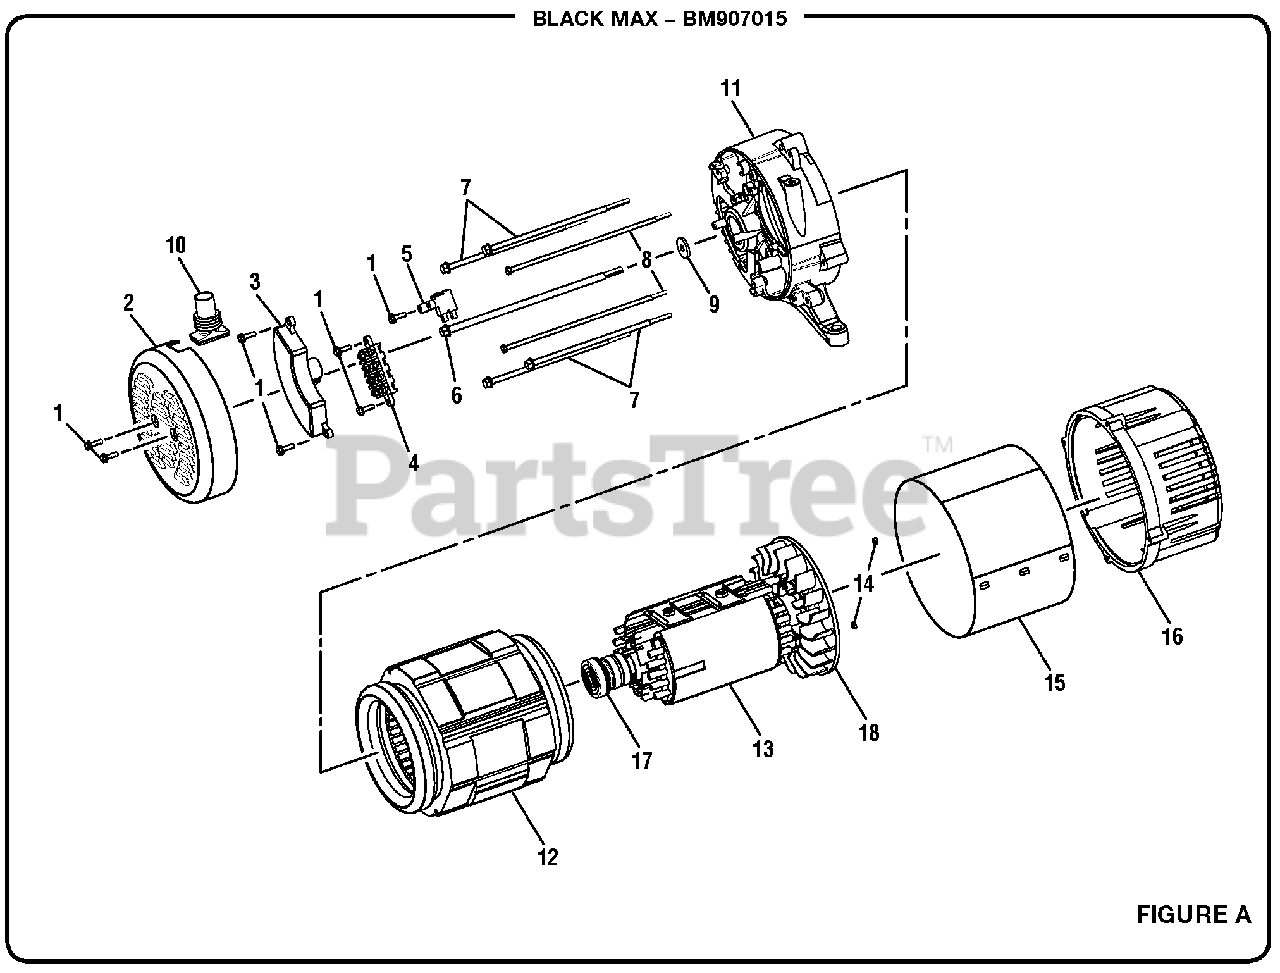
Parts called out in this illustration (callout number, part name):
1	Bolt (M5 x 17 mm, Hex Hd.)
2	Brush Cover
3	Automatic Voltage Regulator
4	Terminal Block
5	Brush Assembly
6	Bolt (5/16-24 x 235 mm, Hex Washer Hd.)
7	Bolt (M6 x 188 mm, Hex Washer Hd.)
8	Bolt (M5 x 170 mm, Hex Washer Hd.)
9	Washer (OD28 x ID10 x 3t)
10	Rubber Boot
11	Bearing Housing
12	Stator Assembly
13	Rotor Assembly
14	Hex Nut (M5)
15	Generator Head Cover
16	Adaptor Housing
17	Ball Bearing
